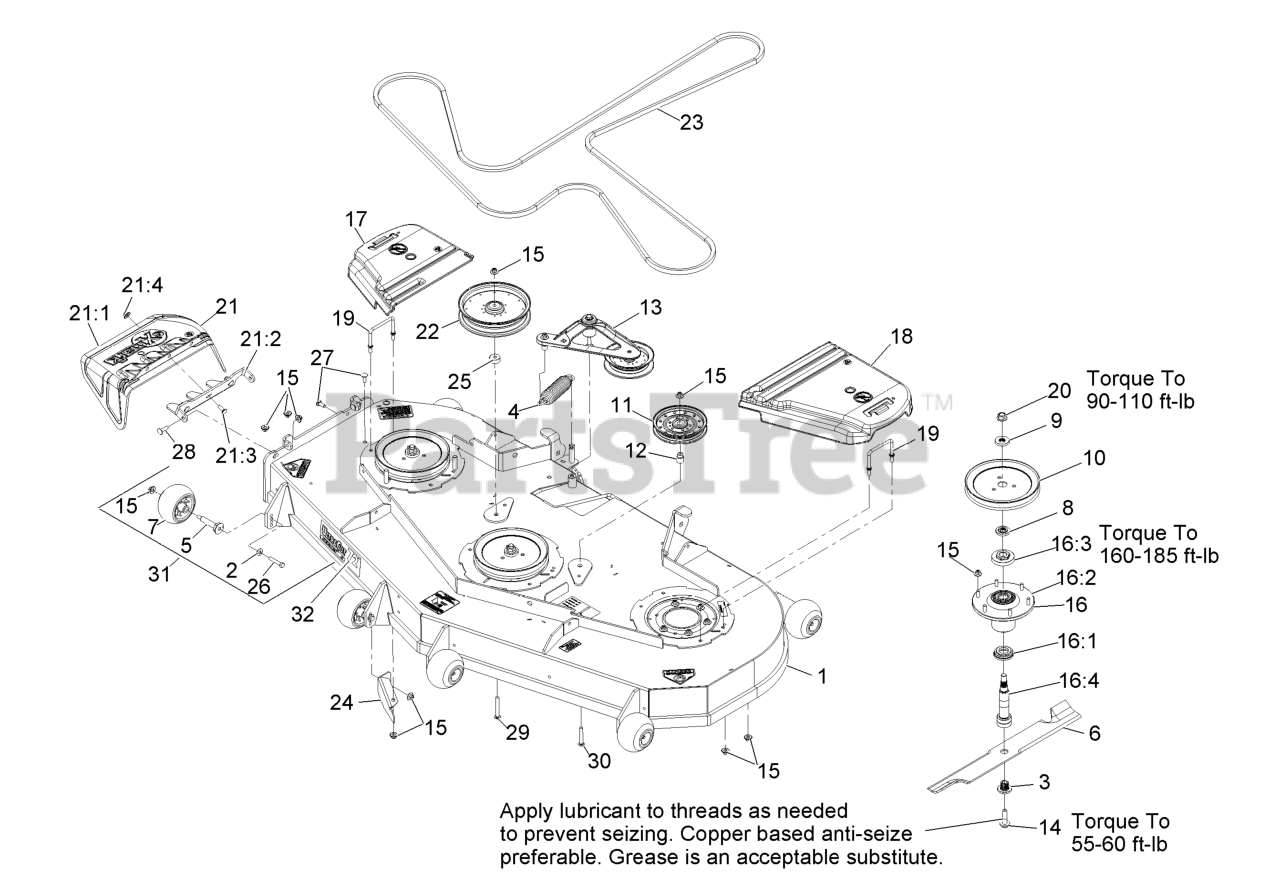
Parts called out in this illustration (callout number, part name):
1	DECK W/ DECALS ASM-72
2	WASHER-BELLEVILLE
3	BUSHING,SPLINED
7	ROLLER-SCALP, ANTI
8	SPACER,SPLINED STEPPED
9	SPACER,SPLINED
10	SHEAVE,BLADE DRIVE 9.00
12	BUSHING-IDLER
13	DECK IDLER ASM
14	SCREW,SEMS 1/2-20 X 2.19
15	Nut-Nyloc 3/8-16 Flg
16	ASM,SPINDLE HOUSING
16:1	GUARD,BOTTOM
16:2	ASM,CUTTER HOUSING
16:3	NUT, SPINDLE 7/8-14
16:4	SPINDLE,DOUBLE SPLINE
17	COVER-BELT, RH
18	COVER-BELT, LH
19	WIREFORM-COVER
20	NUT-FLANGE, CENTERLOCK
21	ASM,DISCHARGE CHUTE
21:1	CHUTE,DISCHARGE
21:2	BRACKET,DISCHARGE CHUTE
21:3	SCREW-CARR
21:4	Nut-Nyloc 3/8-16 Flg
22	PULLEY-IDLER
23	BELT-V
24	BAFFLE,DISCHARGE 726
25	SPACER-IDLER
26	SCREW-HH
27	SCREW-CARR
28	Bolt-Carriage 3/8-16 X 1 1/4
29	SCREW-CARR
30	SCREW-CARR
32	DECAL,ULTRACUT 72 SERIES
